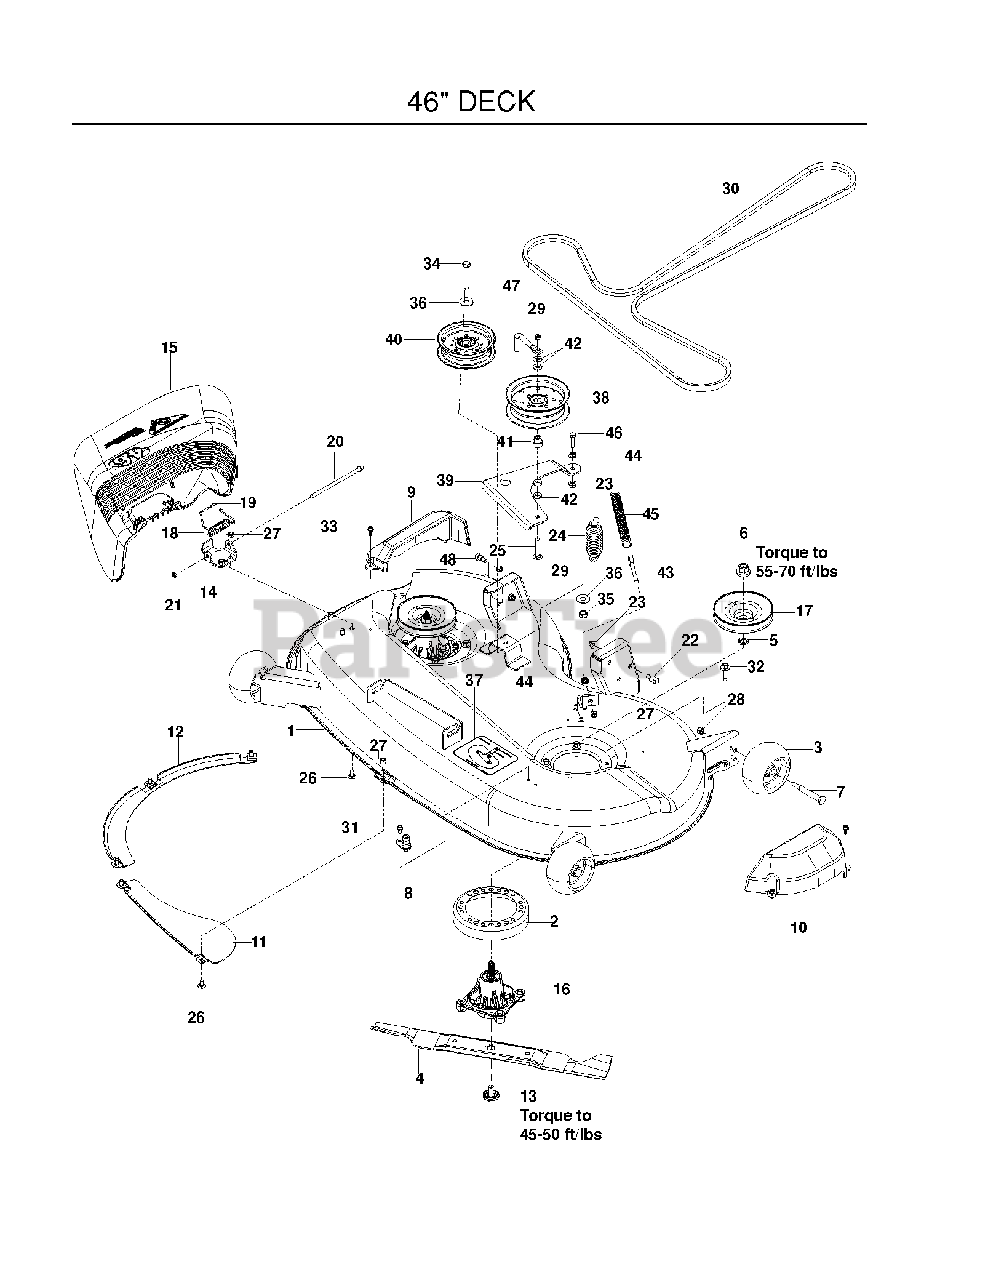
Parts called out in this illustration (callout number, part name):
1	DECK.STAMPED.46".W/DECALS.BLAC
2	STRIPPER-ROUND-UNIVERSAL
3	GAUGE WHEEL
4	BLADE, 46" HI-LIFT
5	WASHER-SPACER
6	LOCKNUT - 9/16
7	SHOULDER BOLT 1/2X2-5/8 ZD SPE
8	PORT.WASHOUT
9	COVER.MANDREL.RH.46"
10	COVER.MANDREL.LH.46"
11	BAFFLE CENTER FRONT
12	BAFFLE FRONT RH
13	BOLT.WASHER.ASM.7/16-2
14	BRKT.DEFLECTOR.38"2005+
15	SHIELD.DEFLECTOR.MOWER.46"BLAC
16	CUTTER HOUSING
17	PULLEY, DECK
18	TORSION SPRING
19	CAP-SLEEVE
20	ROD, HINGE
21	PUSH NUT
22	STUD.FASTNER.W/ANTI-ROTATE
23	5/16-18 NYLOC FLANGE NUT
24	SPRING
25	CARRIAGE BOLT 3/8-16 X
26	BOLT 5/16C X 3/4" CARRIAGE
27	NUT 5/16 NYLOC
28	NUT 3/8-16 NYLOC
29	NUT HEX 3/8-16 NYLON, THIN
31	SCREW #10 X 1/2 SELF TAPPING
32	WASHER HEAD SCREW
33	SCREW- 1/4-20 X 5/8
34	BOLT 7/16-14 X 2-1/2 GR 5 ZD
35	7/16-14 HEX NUT W/NYL RING ZD
36	WASHER 7/16 FLAT ZD
37	DECAL, BELT ROUTING
38	PULLEY, IDLER
39	ARM, IDLER BLK
40	PULLEY.IDLER.MWR.STATIONARY.LH
41	IDLER BUSHING
42	WASHER 3/8 X 3/4 X .187 TK
43	EYE BOLT 5/16 X 3.50
44	NUT 5/16C WHIZ
45	SPRING, DECK BELT
46	HCS 5/16C X 1 1/4
47	BELT KEEPER 5"
48	SB 3/8-16 X 3/8 SKT HD ZD
